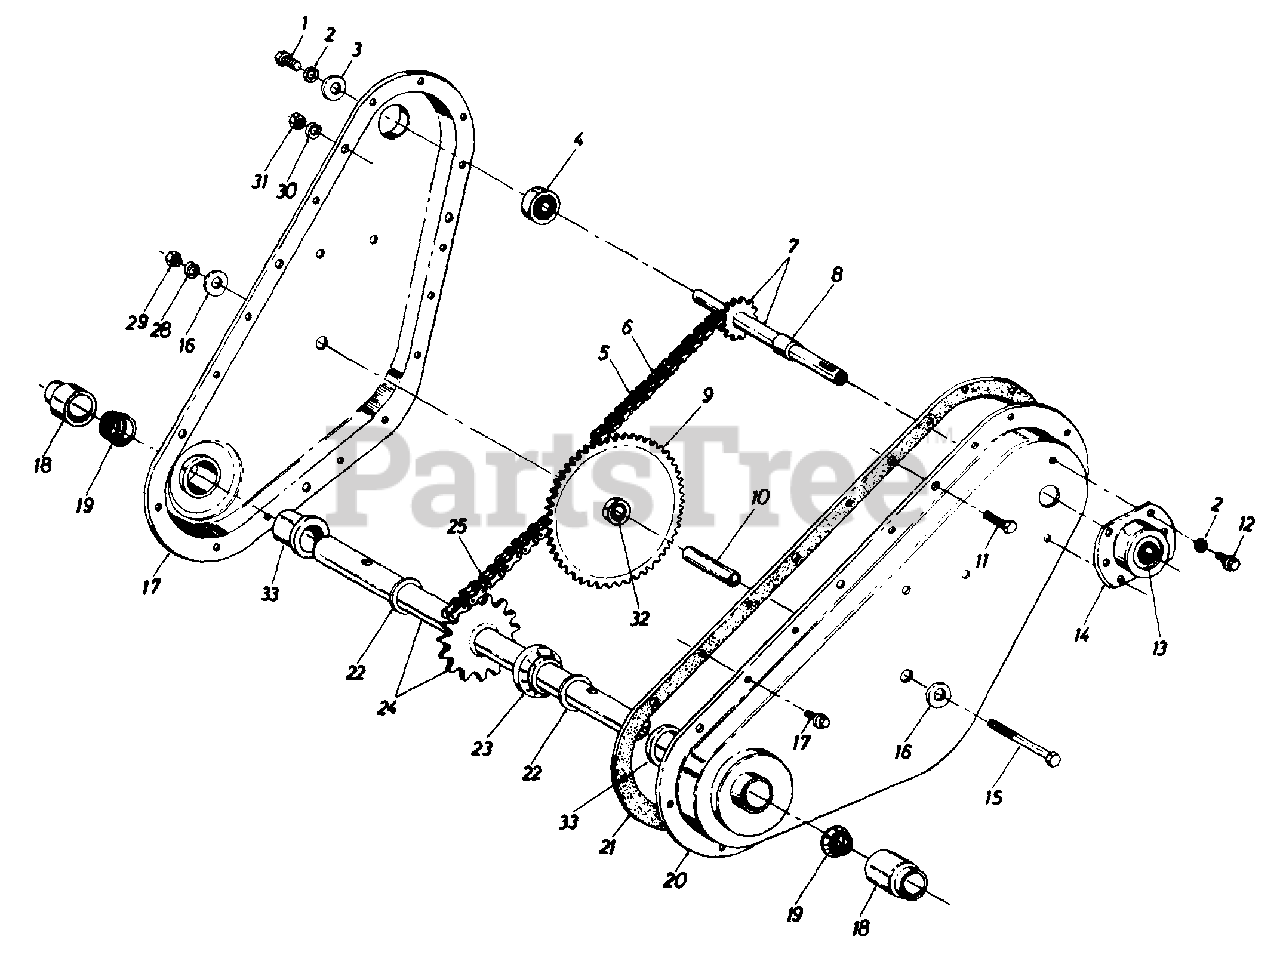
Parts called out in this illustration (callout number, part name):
1	Hex L-Scr. 1/4-28 x .625" Lg.
2	L-Wash. 1/4" Scr.
3	Fl-Wash. .25" I.D. x .93" O.D. x .125" Thk.
4	Bearing .62" I.D. x 1.38" O.D. x .437" Thk.
5	#35 Chain 3/8" Pitch x 70 Links - Endless
6	Master Link
7	Input Shaft Assembly
9	Sprocket Assembly
10	Sprocket Hub Tubing 3/8" I.D. x 5/8" O.D. x 1.9" Lg.
11	Hex Scr. 5/16-18 x .625" Lg.
12	Hex Wash. Hd. Self-Tap Scr. 1/4-20 x .50" Lg.
13	Bearing .625" I.D. x 1.38" O.D. x .437" Thk.
14	Bearing Housing
15	Hex Scr. 3/8-24 x 2.75" Lg.
16	Fl-Wash. 3/8" I.D. x 1.25" O.D. x .100 Thk.
17	Hex Wash. Hd. Self-Tap Scr. 1/4-20 x .50" Lg.
18	Dust Cap
20	Tiller Housing - L.H.
21	Gasket
22	Thrust Wash. 1.00" I.D. x .030" Thk.
23	Step Spacer
24	Tine Shaft Assembly
25	#50 Chain 5/8" Pitch x 38 Links - Endless
28	L-Wash. 3/8" Scr.
29	Hex Nut 3/8-24 Thd.
30	L-Wash. 5/16" Scr.
31	Hex Nut 5/16-18 Thd.
32	Bearing
33	Bearing
